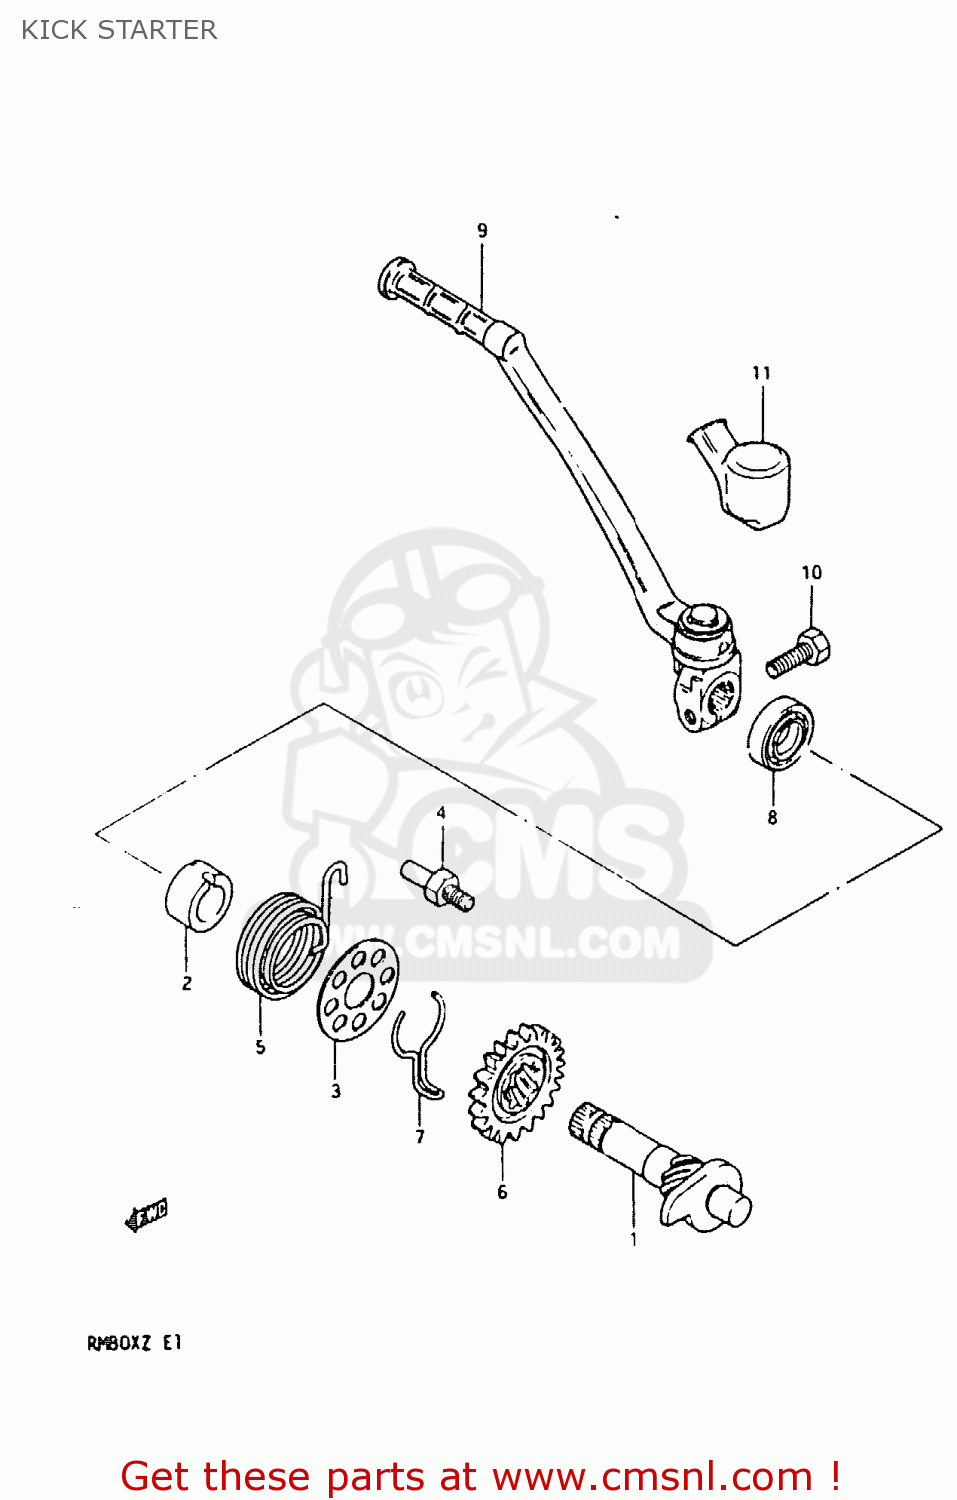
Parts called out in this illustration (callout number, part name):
1	SHAFT,KICK STARTER
2	GUIDE,KICK STARTER SFT SPRING
3	HOLDER,KICK STARTER SHAFT SPR
4	BOLT,KICK START SHAFT SPR HOOK
5	SPRING
6	GEAR,KICK STARTER DRIVE
7	SPRING,RETAINER
8	SEAL,OIL(14X24X6)
9	LEVER ASSEMBLY,KICK STARTER
10	BOLT
11	COVER,KICK LEVER JOINT
